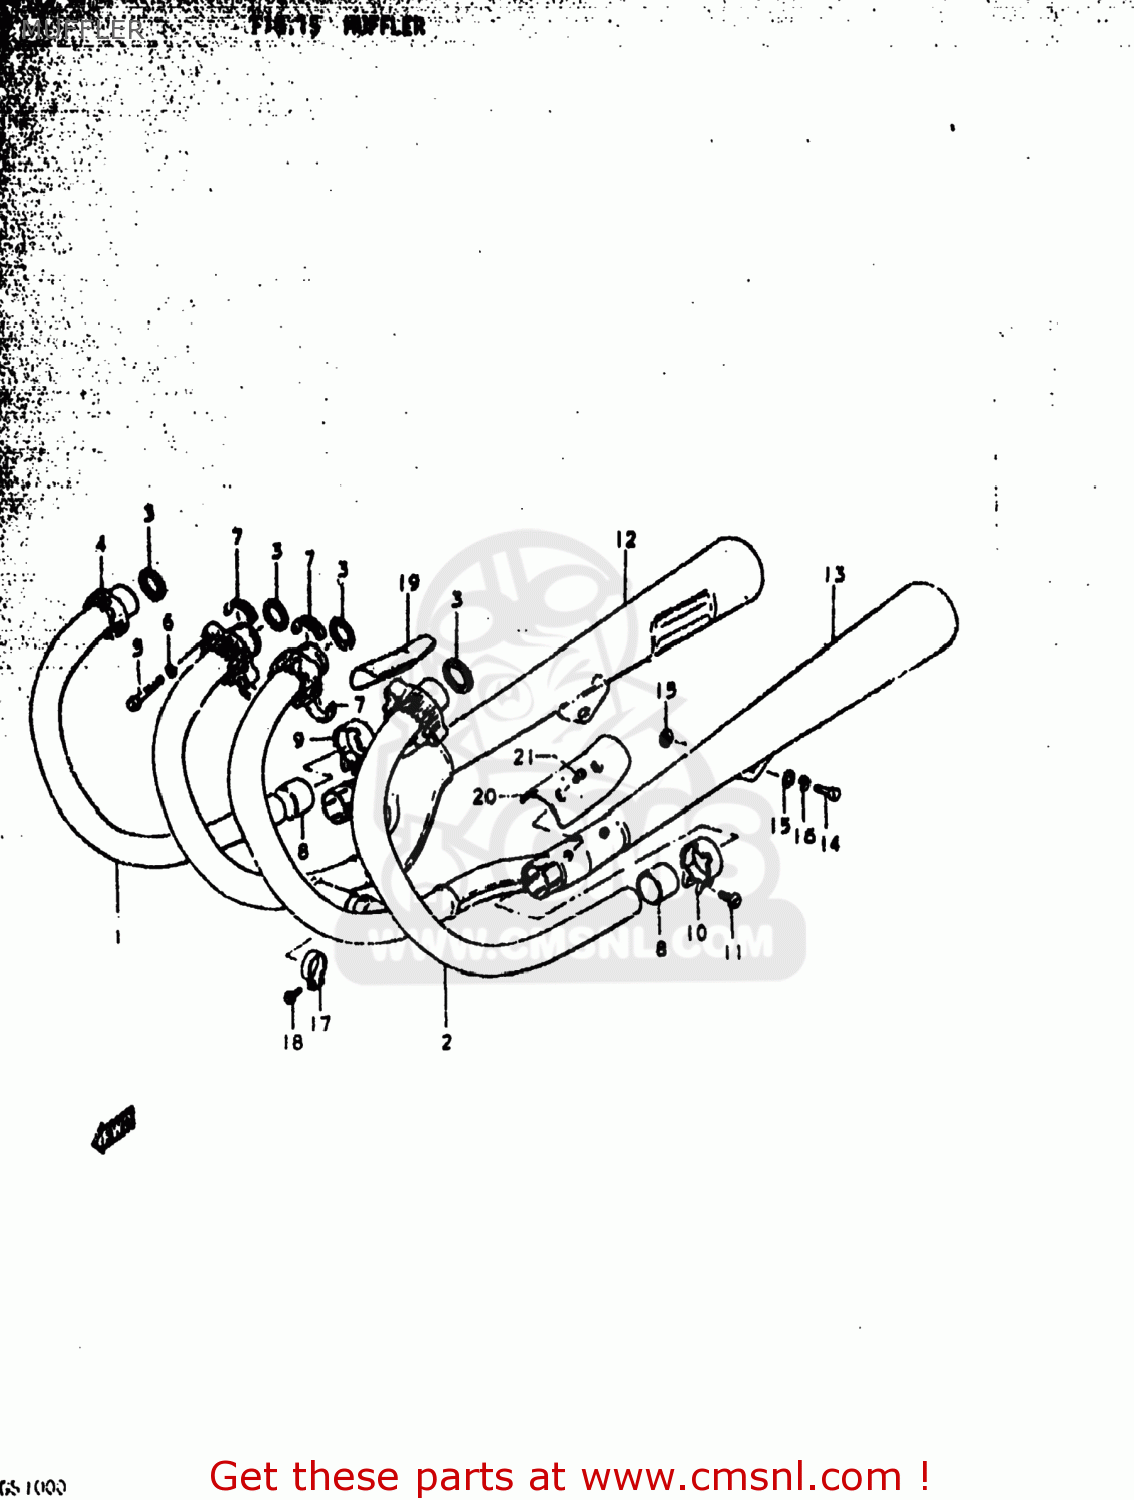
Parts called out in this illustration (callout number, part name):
1	PIPE,EXHAUST,R
2	PIPE,EXHAUST,L
3	GASKET,EXHAUST PIPE (NAS)
4	CLAMP,EXHAUST PIPE
5	BOLT
6	LOCK WASHER
7	PLATE,EXHAUST
8	CONNECTOR,MUFFLER
9	CLAMP,MUFFLER CONNECTOR,R
10	CLAMP,MUFFLER CONNECTOR,L
11	BOLT
12	BODY,MUFFLER
13	BODY,MUFFLER
14	BOLT 10X30
15	WASHER
16	LOCK WASHER
17	CLAMP
18	BOLT
19	COVER,MUFFLER
20	COVER,MUFFLER,LEFT
21	SCREW
